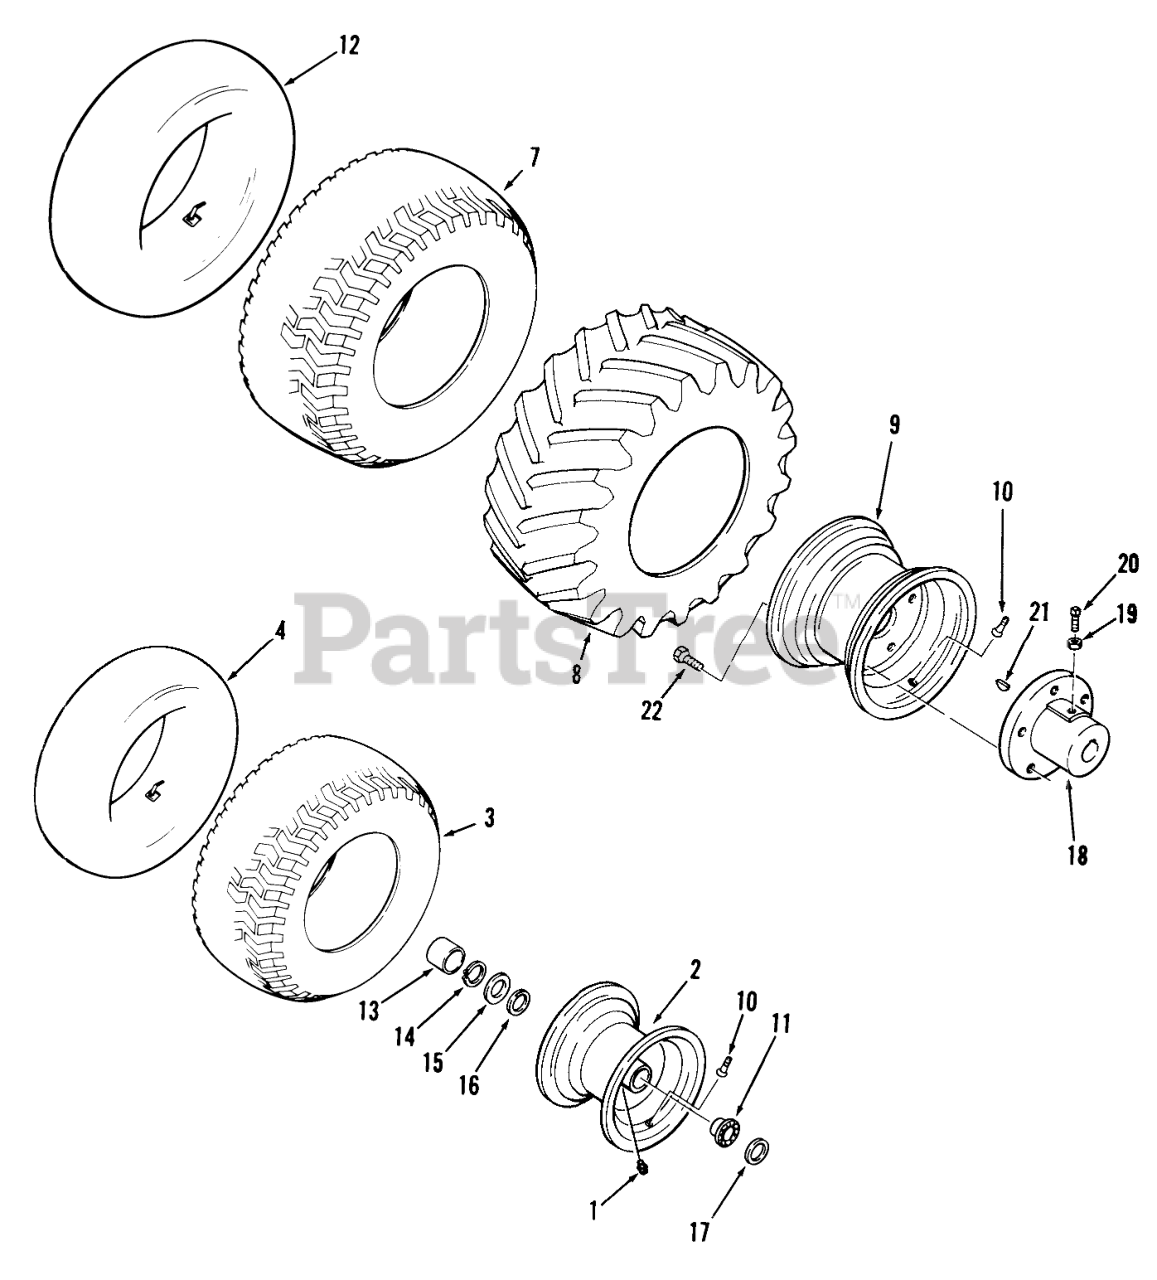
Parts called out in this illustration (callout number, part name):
1	Zerk
2	WHEEL ASSY
3	TIRE TURF SAVER 16X6.50-8
4	TUBE-INNER
7	Tire
8	Tire-Cleat, Rear
9	Wheel
10	VALVE
11	Bearing
12	TUBE-INNER
13	HUB CAP
14	Snap Ring
15	Washer
16	WASHER
17	WASHER-SHIM
18	Hub Rear
19	Nut
20	Screw-Set
21	KEY-WOODRUFF
22	Lug Nut
